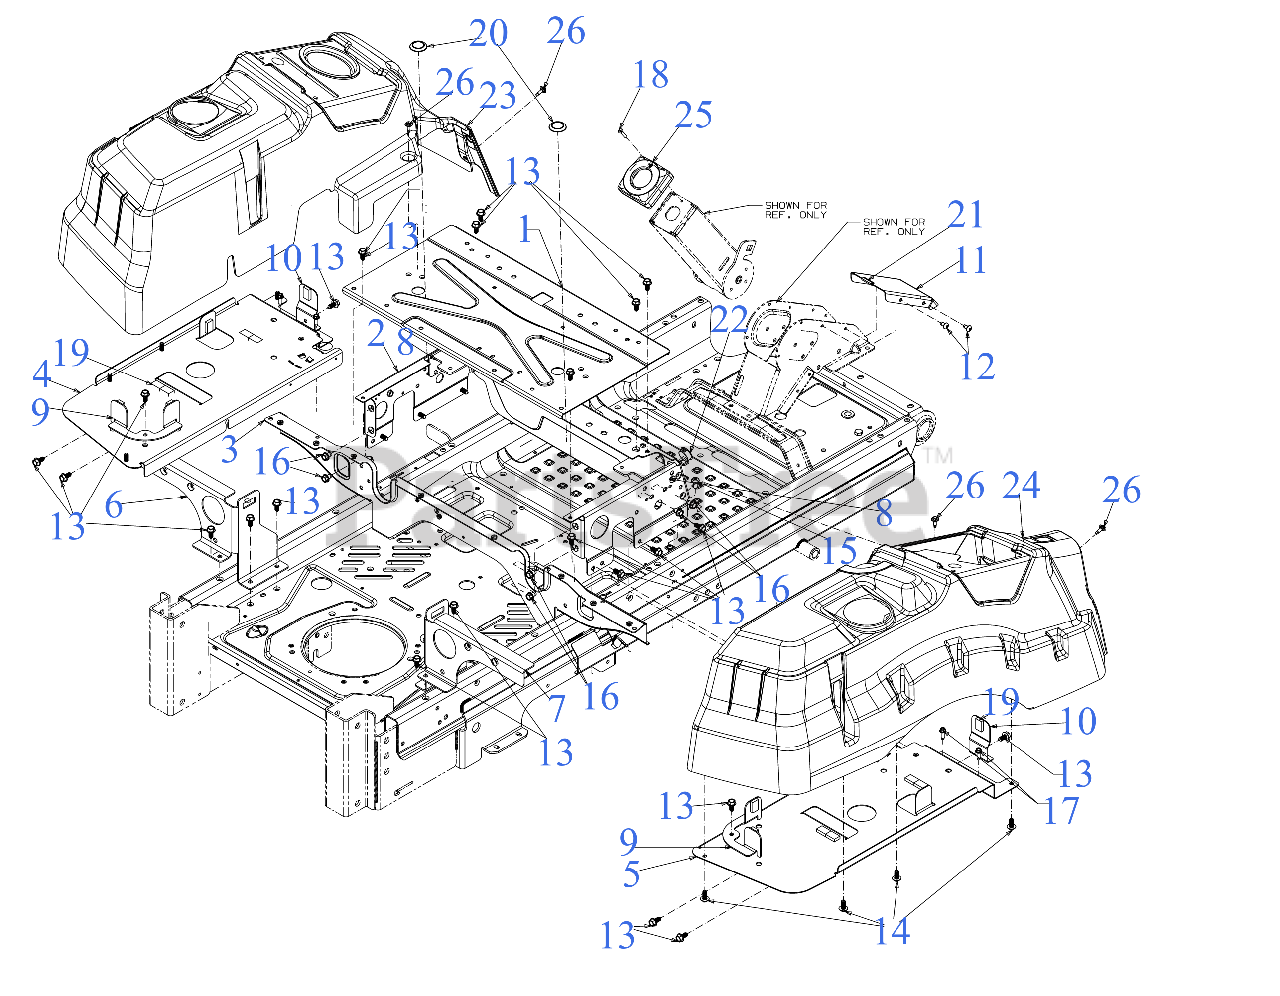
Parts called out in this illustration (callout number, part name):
8	SEAT BOX BRACKET
12	SCREW 1/4-20 x .500
13	SCREW 5/16-18 x .750
14	SCREW 5/16-14 x .750
15	SCREW 5/16-18 x .750
16	SCREW 5/16-18 x .500
17	SCREW 1/4-20 x .750
18	SCREW #10-16 x 1.25
19	FOAM TAPE .625 WIDE x .25 THK BULK
21	TRIM STRIP 10"
22	PLASTIC PLUG
23	CONSOLE (LH) Z-STYLE
24	CONSOLE (RH) Z-STYLE
25	STEERING COLUMN COVER
26	SHOULDER SCREW M6-1 .368 X.115
